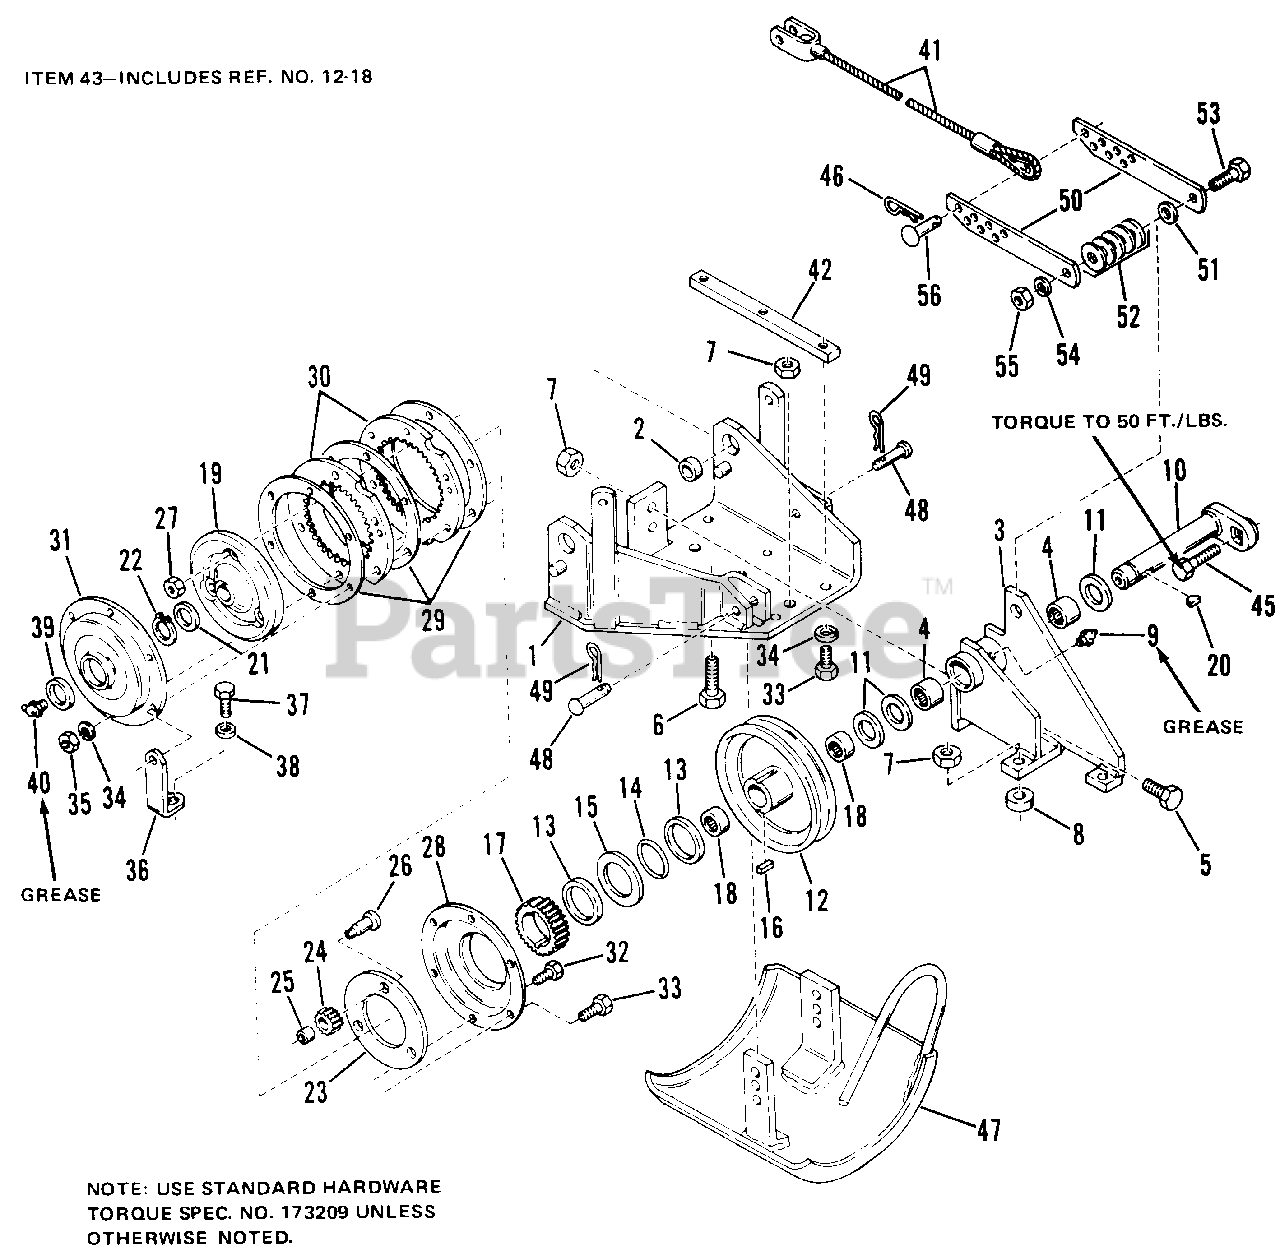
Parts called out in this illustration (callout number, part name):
1	PLATE ASSY, Mounting
3	HOUSING SUB ASSY, Bearing
5	CAPSCREW, Hex Hd., 7/16-14 x 1-1/4
6	CAPSCREW, Hex Hd., 7/16-14 x 1-3/4
7	NUT, Hex, Full Lock, 7/16-14
9	FITTING, Lube, 1/4-28
10	CRANKSHAFT
12	HUB & PULLEY
17	GEAR, Sun
19	HUB, Spider
20	KEY, Woodruff, No. 9
22	RING, Retaining
23	RING, Bolt
25	BEARING, Needle
26	PIN, Pinion
27	NUT, Hex, Full Lock, Jam, 5/16-18
28	COVER, L.H.
30	GEAR, Ring
32	CAPSCREW, Hex Hd., 5/16-18 x 3/4
33	CAPSCREW, Hex Hd., 5/16-18 x 7/8
34	LOCKWASHER, Spring, 5/16
35	NUT, Hex, 5/16-18
37	CAPSCREW, Hex Hd., 5/16-18 x 1
38	WASHER, Plain, 1/4
40	FITTING, Lube, Elbow 90, 1/4-28
41	CABLE ASSY
42	BAR, Spacer
43	PULLEY & HUB ASSY (Incl. Ref. nos. 12-18)
44	HOUSING SUB ASSY, Bearing
45	CAPSCREW, Hex Hd., 7/16-14 x 2-1/4
46	CLIP, Spring
47	SHOE ASSY
49	CLIP, Spring
51	SPACER, Pinion
53	CAPSCREW, Hex Hd., 3/8-16 x 1-1/2
54	LOCKWASHER, Spring, 5/16
55	NUT, Hex, 3/8-16
